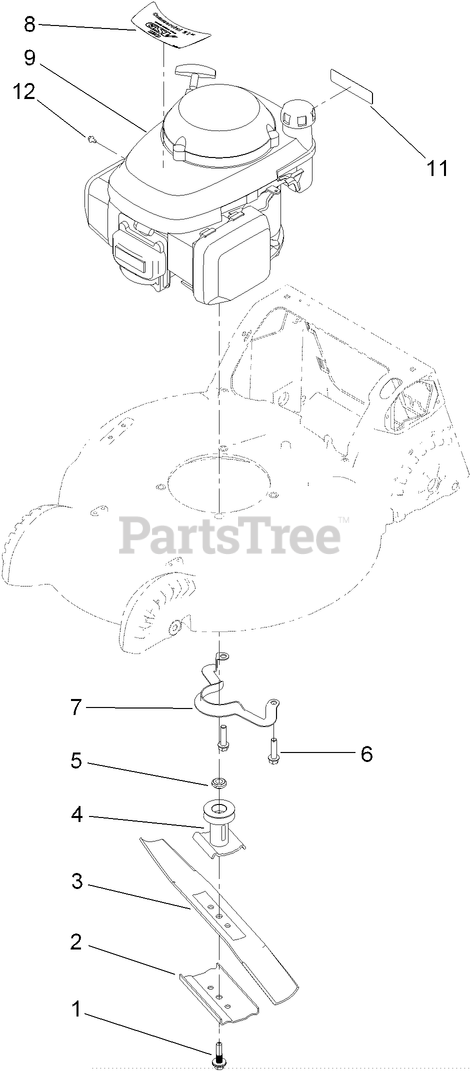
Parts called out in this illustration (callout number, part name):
1	BOLT-BLADE
2	SUPPORT-BLADE
3	BLADE-BAGGING
4	DRIVER-BLADE
5	Spacer-Driver
6	SCREW-HWH
7	GUIDE-BELT
8	DECAL-ENGINE
11	DECAL-ARRESTER, SPARK
12	SCREW-HWH
